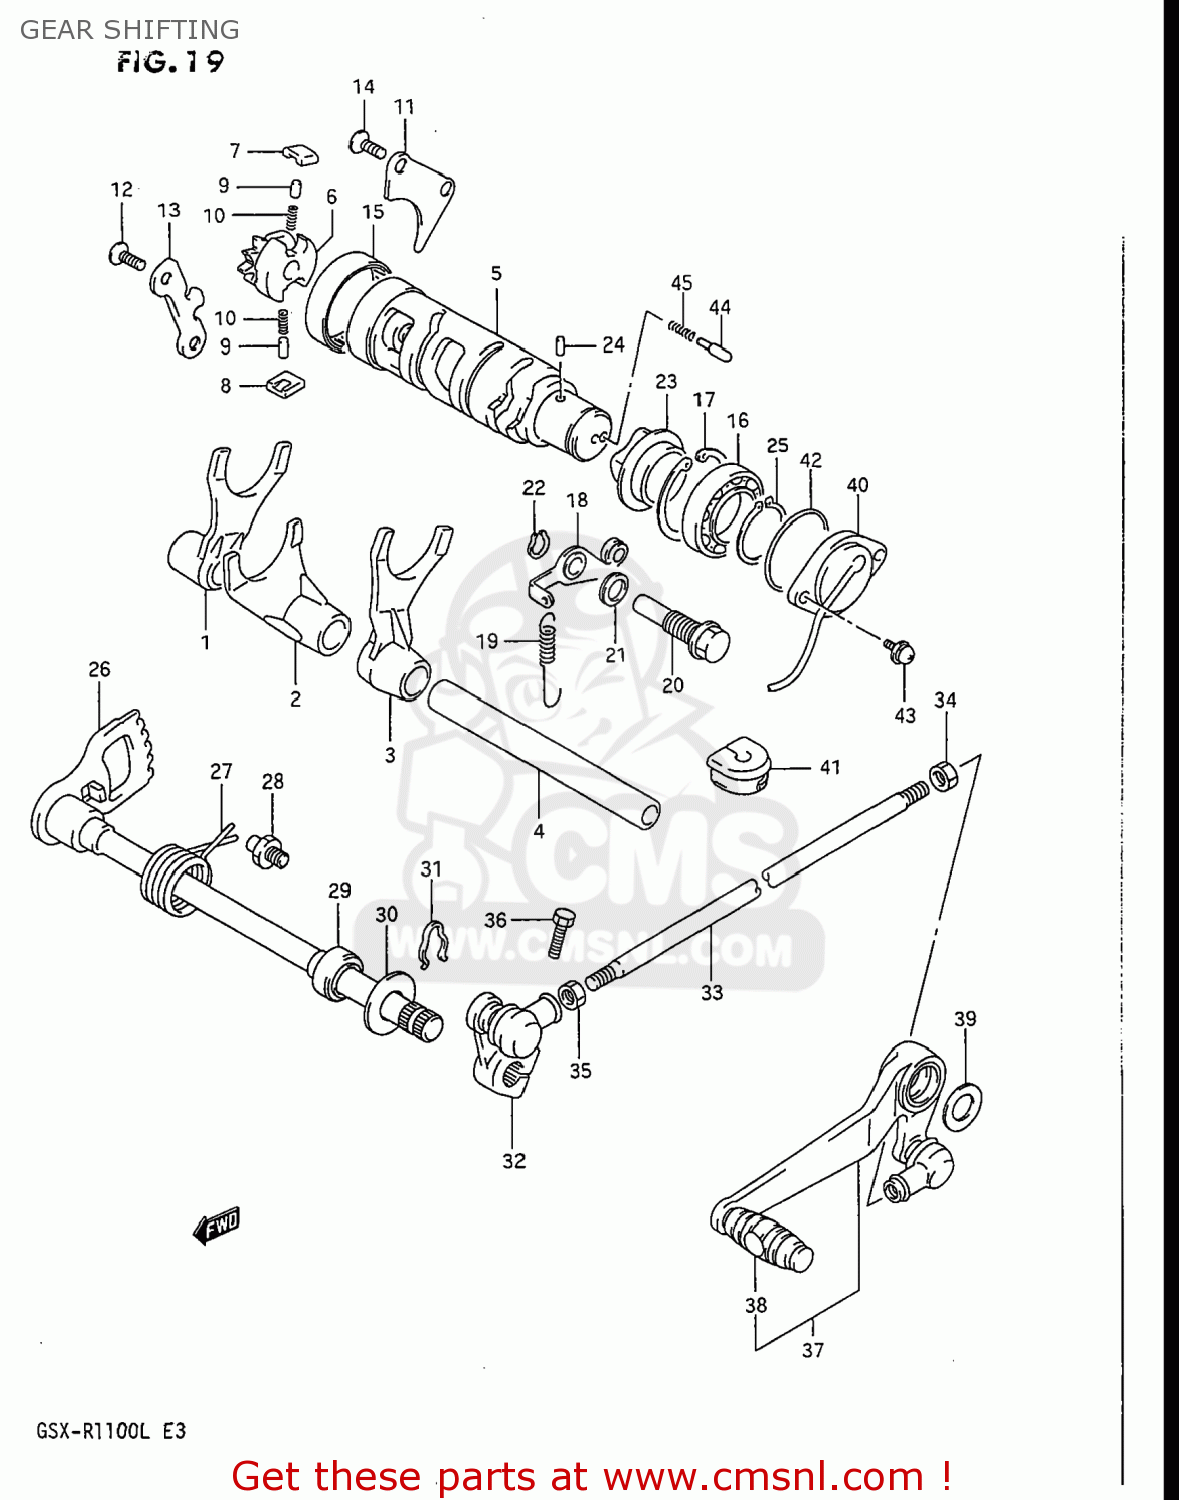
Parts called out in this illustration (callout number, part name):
1	FORK,GEAR SHIFT NO.1
2	FORK,GEAR SHIFT NO.2
3	FORK,GEAR SHIFT NO.3
4	SHAFT,GEAR SHIFT FORK(L:128)
5	CAM,GEAR SHIFT
6	GEAR,GEARSHIFT CAM DRIVE
7	PAWL,GEAR SHIFT NO.1
8	PAWL,GEAR SHIFT NO.2
9	PIN(5X8)
10	SPRING
11	LIFTER,GEAR SHIFT PAWL
12	SCREW
13	GUIDE,GEAR SHIFT CAM
14	SCREW
15	BEARING(43X49X12)
16	BALL BEARING
17	CIRCLIP,42MM
18	STOPPER,GEAR SHIFT CAM
19	SPRING
20	SHAFT,GEAR SHIFT CAM STOPPER
21	GASKET(10X14X3.6) (NAS)
22	CIRCLIP
23	PLATE,STOPPER
24	PIN 4X6
25	CIRCLIP,25MM
26	SHAFT,GEAR SHIFT
27	SPRING
28	STOPPER,GEAR SHIFT CAM
29	OIL SEAL
30	WASHER (12.5X27X1.6)
31	SPRING,RETAINER
32	ARM,GEAR SHIFT
33	ROD,GEAR SHIFT LINK
34	NUT
35	NUT 6MM
36	BOLT
37	LEVER ASSEMBLY,GEAR SHIFTING
38	RUBBER,GEAR SHIFT PEDAL
39	WASHER(18X24X1)
40	BASE ASSY,GEAR SHIFT TERMINAL
41	GROMMET,LEADWIRE
42	O RING(D:2.4,ID:36.5)
43	SCREW
44	PIN(5X15.5)
45	SPRING
